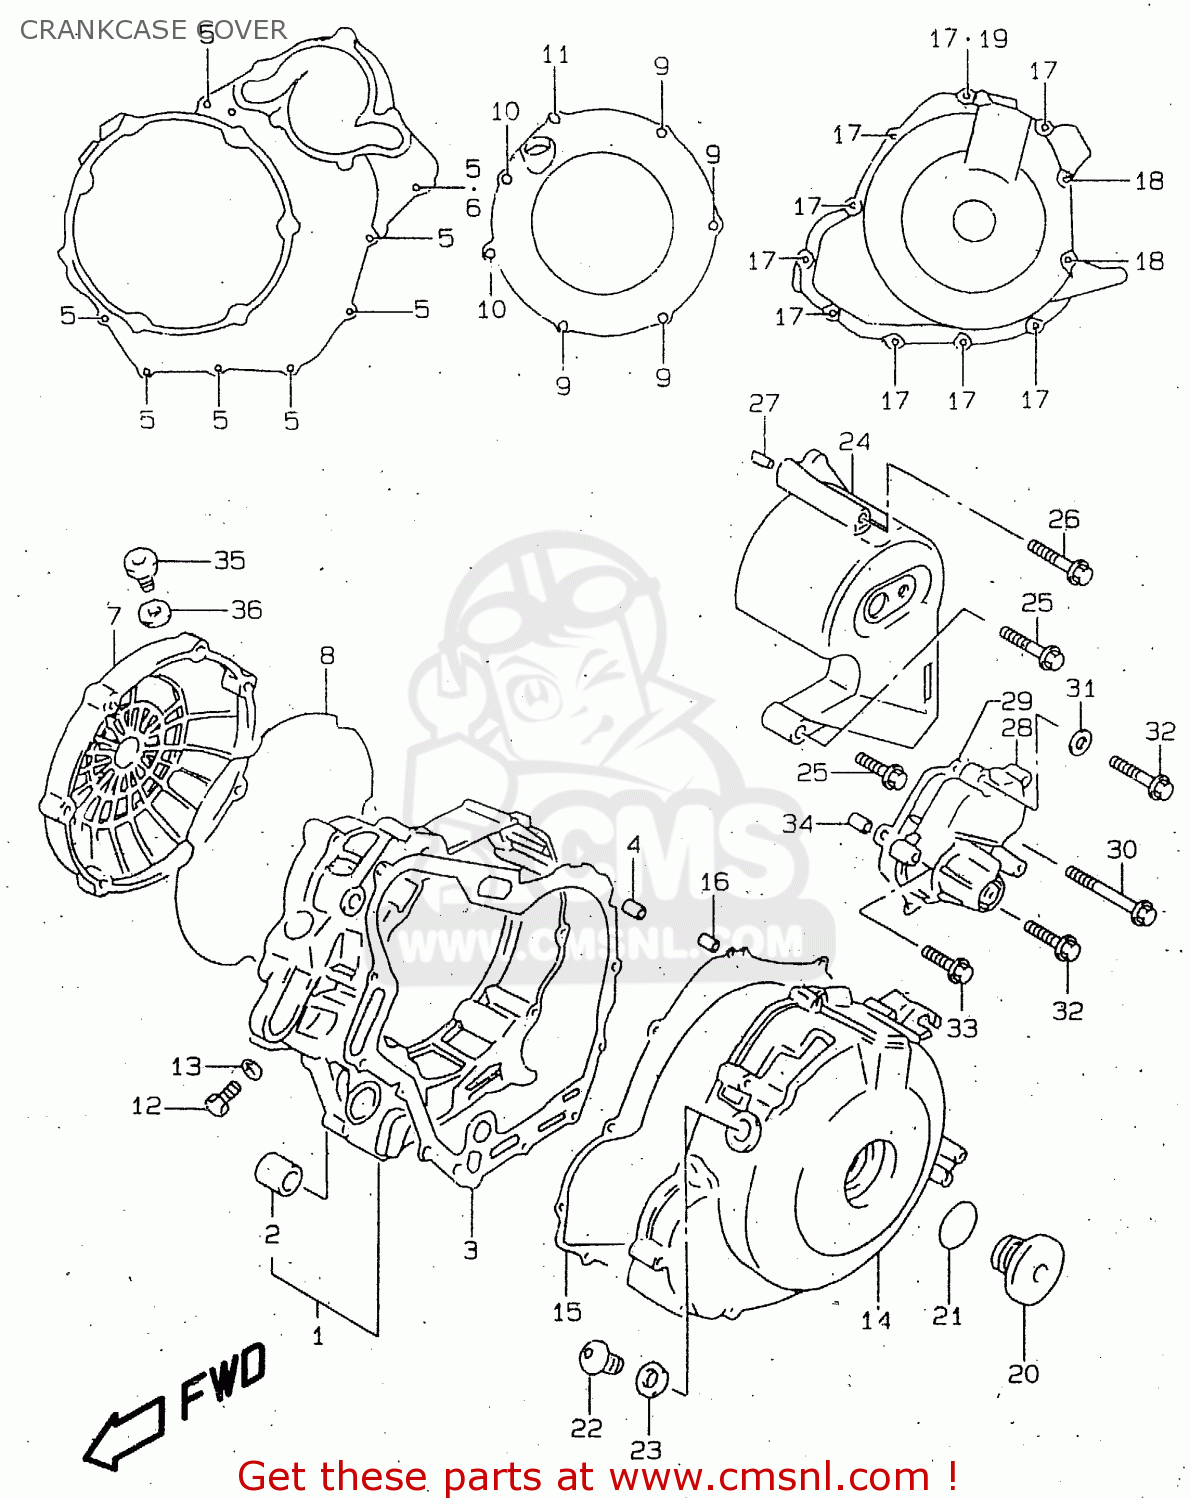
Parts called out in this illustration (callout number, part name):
1	COVER,CLUTCH
2	LENS,OIL LEVEL CHECK
3	GASKET,CLUTCH COVER (NAS)
4	PIN
5	BOLT,G/S SWITC
6	GASKET(5.8X11X1.2) (NAS)
7	COVER,CLUTCH OUTER
8	O RING,CLUTCH COVER OUTER
9	BOLT
10	BOLT
11	BOLT
12	BOLT
13	GASKET(6.2X11X1).2 (NAS)
14	COVER,MAGNETO
15	GASKET,MAGNETO COVER (NAS)
16	PIN
17	BOLT
18	BOLT
19	GASKET(5.8X11X1.2) (NAS)
20	PLUG
21	O RING(D:3.1,ID:32.7)
22	PLUG,14X12
23	GASKET(13.8X18.8X4.8) (NAS)
24	COVER,ENGINE SPROCKET
25	BOLT
26	BOLT
27	PIN
28	COVER,GEAR SHIFT
29	GASKET,GEAR SHIFT COVER (NAS)
30	BOLT(6X105)
31	GASKET(5.8X11X1.2) (NAS)
32	BOLT
33	BOLT
34	PIN
35	PLUG
36	O RING(D:3.1,ID:16.8)
